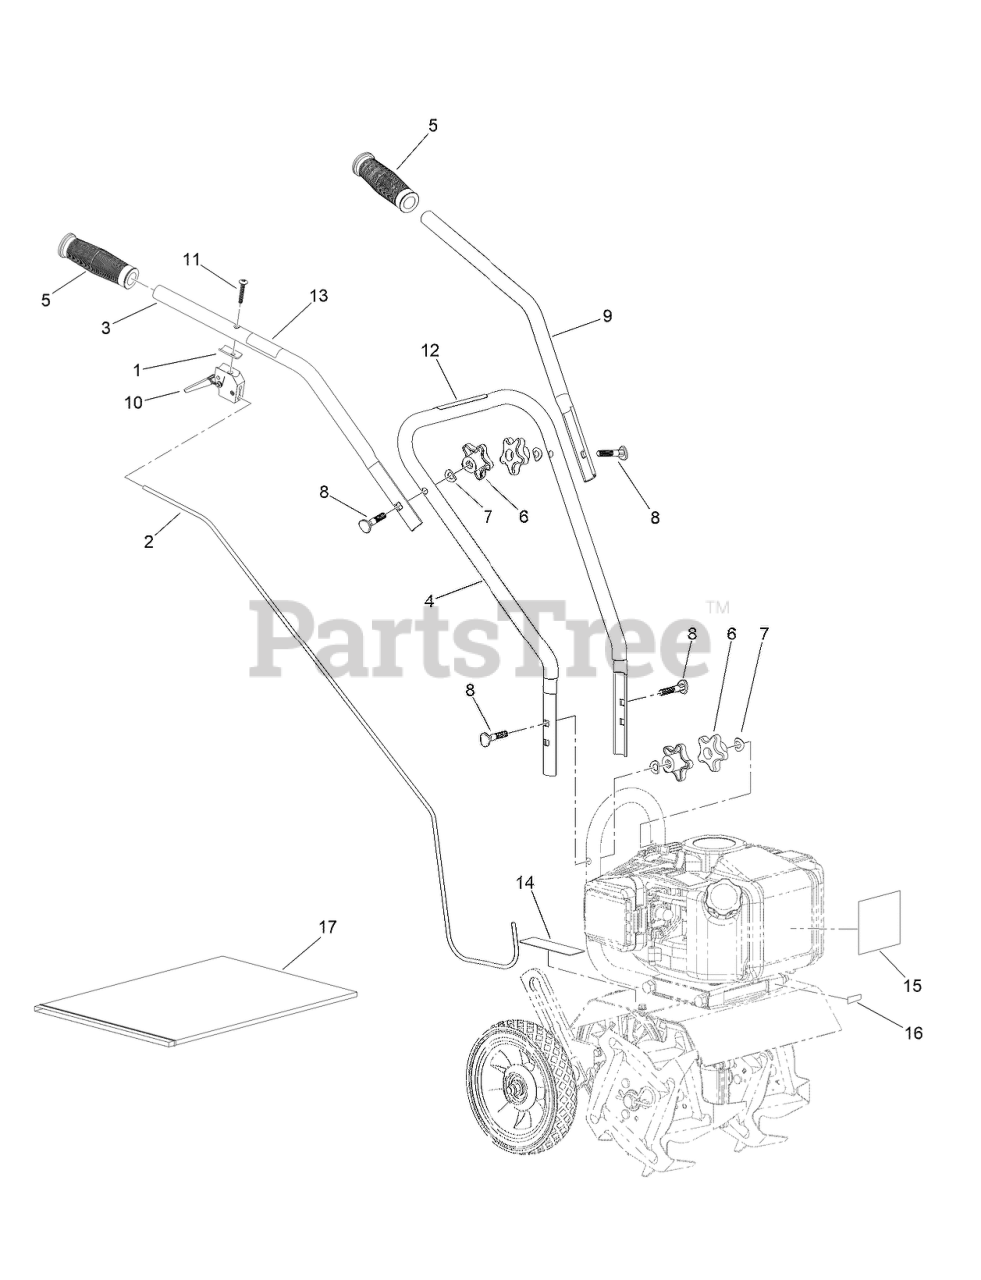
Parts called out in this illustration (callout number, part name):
1	PAD-RUBBER
2	THROTTLE CABLE
3	HANDLE-LOWER
4	HANDLEBAR-MIDDLE
6	KNOB-HANDLE
7	WASHER-SPRING
9	HANDLEBAR-LEFT, UPPER
10	THROTTLE LEVER ASM
11	SCREW-PTH
12	DECAL-QUICK START
13	DECAL-CONTROL, THROTTLE
14	DECAL-WARNING
15	DECAL-TANK, FUEL
16	DECAL-ARRESTOR, SPARK
17	MANUAL ASM
